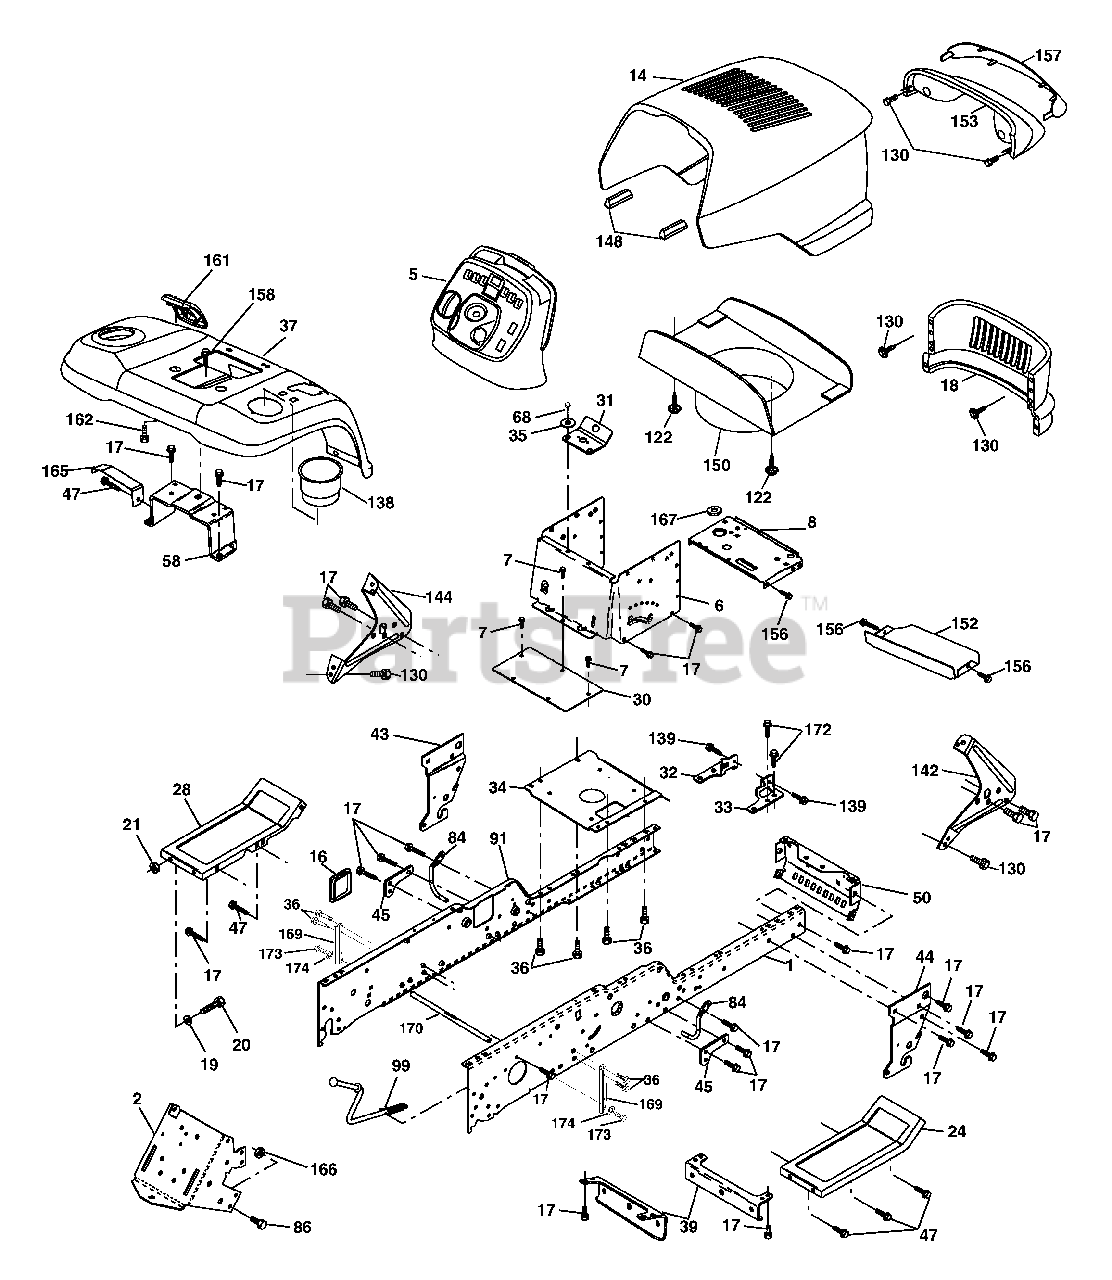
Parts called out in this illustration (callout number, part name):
1	Rail, Frame RH
2	Drawbar, Gt
5	Dash
6	Dash Asm., Lower
7	Screw, Thd Cut 1/4-20 x 1/2
8	Support, Battery
14	Hood Asm., Pnt
16	Cover, Access
17	Screw, 3/8-16 x 3/4
18	Grille
19	Washer 13/32 x 13/16 x 12 Ga.
20	Bolt, Fin Hex 3/8-16 x 1
21	Nut, Lock Hex w/Ins. 3/8-16 unc
24	Footrest, RH
28	Footrest, LH
30	Saddle, Hydro 1995
31	Bracket, Supt 1-pc VGT Steering
32	Bracket, Pivot Chassis LH
33	Bracket, Pivot Chassis RH
34	Plate Asm. Engine Chassis
35	Washer 11/32 x 11/16 x 16 Ga.
36	Screw 5/16-18 x 3/4
37	Fender, Pnt.
39	Bracket, Axle Front
43	Bracket, Spnsn Front Lh
44	Bracket, Spnsn Front Rh
45	Bracket Arm Susp.
47	Screw Thdrol 3/8-16 x 1/2 TYT
50	Bracket, Chassis Front
58	Bracket Asm., Fender
68	Screw, Thd 5/16-18 x 1/2
84	Upstop
86	Bolt, Fin Hex 7/16-14 unc x 1
91	Rail, Frame Lh
99	Rod By Pass
122	Screw Hex Wshd 10-32 x 5/8
130	Screw 10 x 3/4 Single Lead Hex
138	Cupholder YTGT
139	Bolt Shoulder 5/16-18 TT
142	Bracket Dash RH
143	Skirt Grill RH
144	Bracket Dash LH
146	Skirt Grill LH
148	Extrusion Bumper
150	Duct Heat Hood
152	Shield Browning
153	Light Box Asm. w/Lens
156	Screw 5/16-18 x 3/4
157	Lens, Bar
158	Screw Thdrol 3/8-16 x 1/2
159	Screw 3/8-16 x 3/4
161	Console Fuel Window
162	Screw 1/4-1/2
165	Bracket Support Tank
166	Nut, Crownlock 7/16-14 unc
167	Bushing
169	Bracket Chassis Sway
170	Rod Bracket Sway Brace
172	Screw 3/8-16 x .875
173	Bolt Hex 5/16-18 unc x 3/4
174	Washer Lock 5/16
